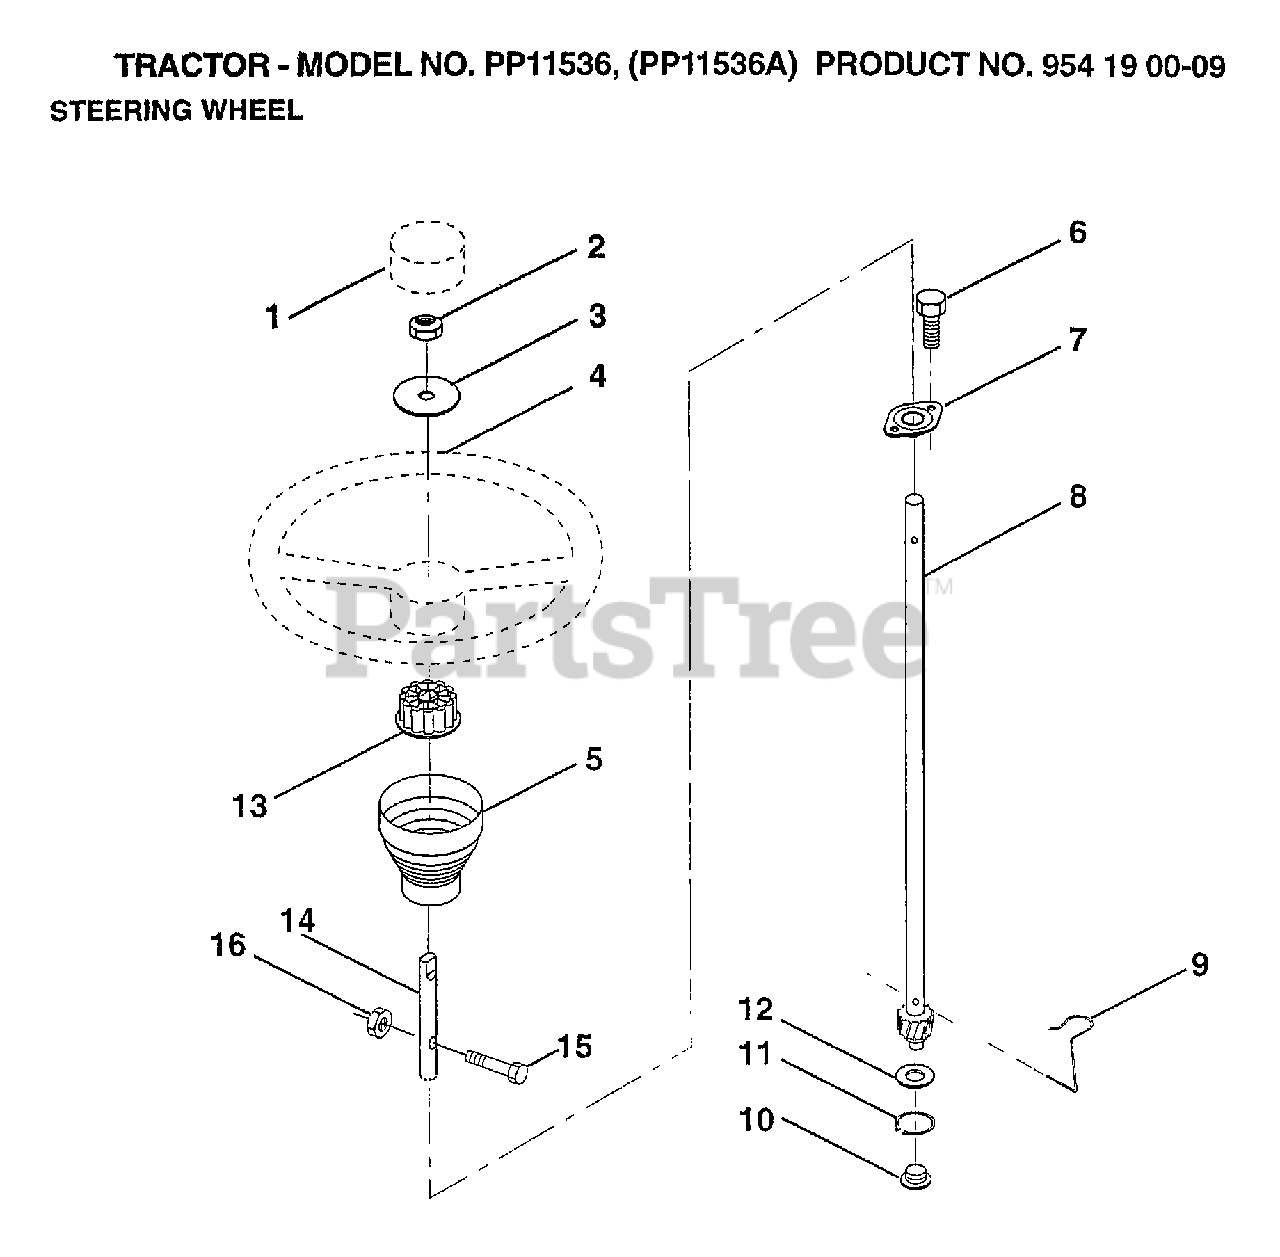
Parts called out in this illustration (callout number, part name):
1	ST WHL INSERT CAP
2	LOCKWASHER
3	WASHER T
5	SLEEVE STEERING
6	"SCREW-TT,10-32 FL"
7	BUSHING.STR.623
8	SHAFT.STEERING.LR
9	STEERING CLIP
10	BUSHING STEER LWR
11	RING
12	WASHER LT
13	ADAPTER LT
14	EXT SHAFT STEERIN
15	BOLT FIN HEX 5/16-18 UNC X 1-1/4
16	LOCKNUT
17	BOLT
